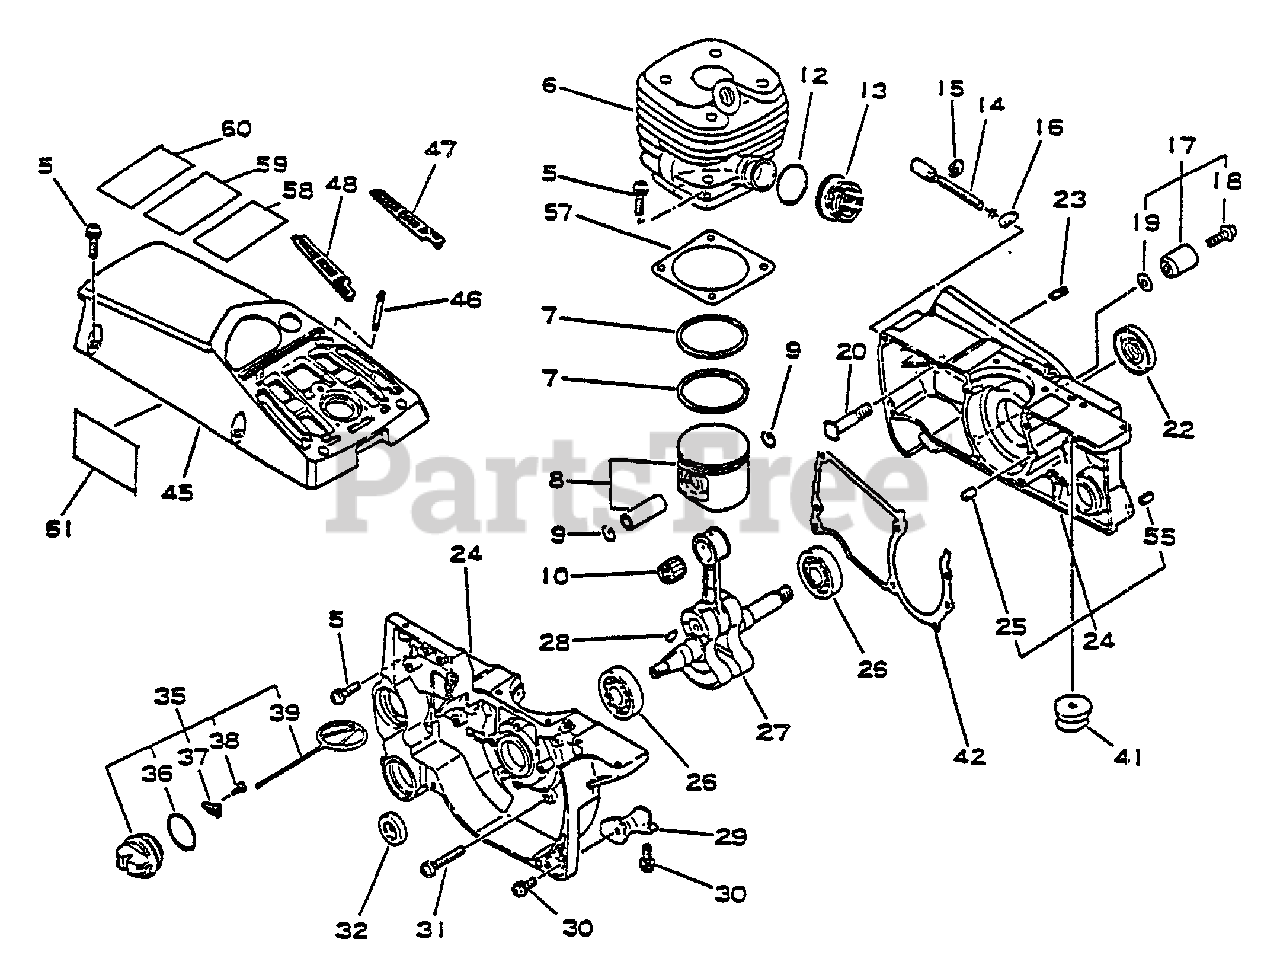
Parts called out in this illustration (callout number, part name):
5	SCREW - 5X20
6	CYLINDER KIT
7	RING, PISTON
8	PISTON KIT
9	RING, RETAINING
10	BEARING, NEEDLE
13	BELLOWS, INTAKE
14	SCREW, TENSIONER
16	TENSIONER, CHAIN
17	CHAIN CATCHER KIT
18	SCREW - 5X20
19	WASHER - 5
20	STUD, GUIDE BAR
22	SEAL, OIL
23	VENT, TANK
24	CRANKCASE KIT - GRAY
25	PIN - LOCATING
26	BEARING, BALL - 6202
27	CRANKSHAFT ASSY
30	SCREW - 5X14
31	SCREW - 5X35
32	SEAL, OIL
35	CAP ASSY
36	O-RING - 25
37	RETAINER
38	SCREW - 3X8
39	CONNECTOR, CAP
41	CUSHION - A
42	GASKET, CRANKCASE
45	COVER, ENGINE - GRAY
46	STUD
47	DEBRIS FILTER KIT
48	DEBRIS FILTER KIT
55	PIN - SPRING -- 5X10
57	GASKET, CYLINDER
58	LABEL - CAUTION
59	LABEL - CAUTION
60	LABEL - BAR & CHAIN
61	LABEL - EYE CATCHER
